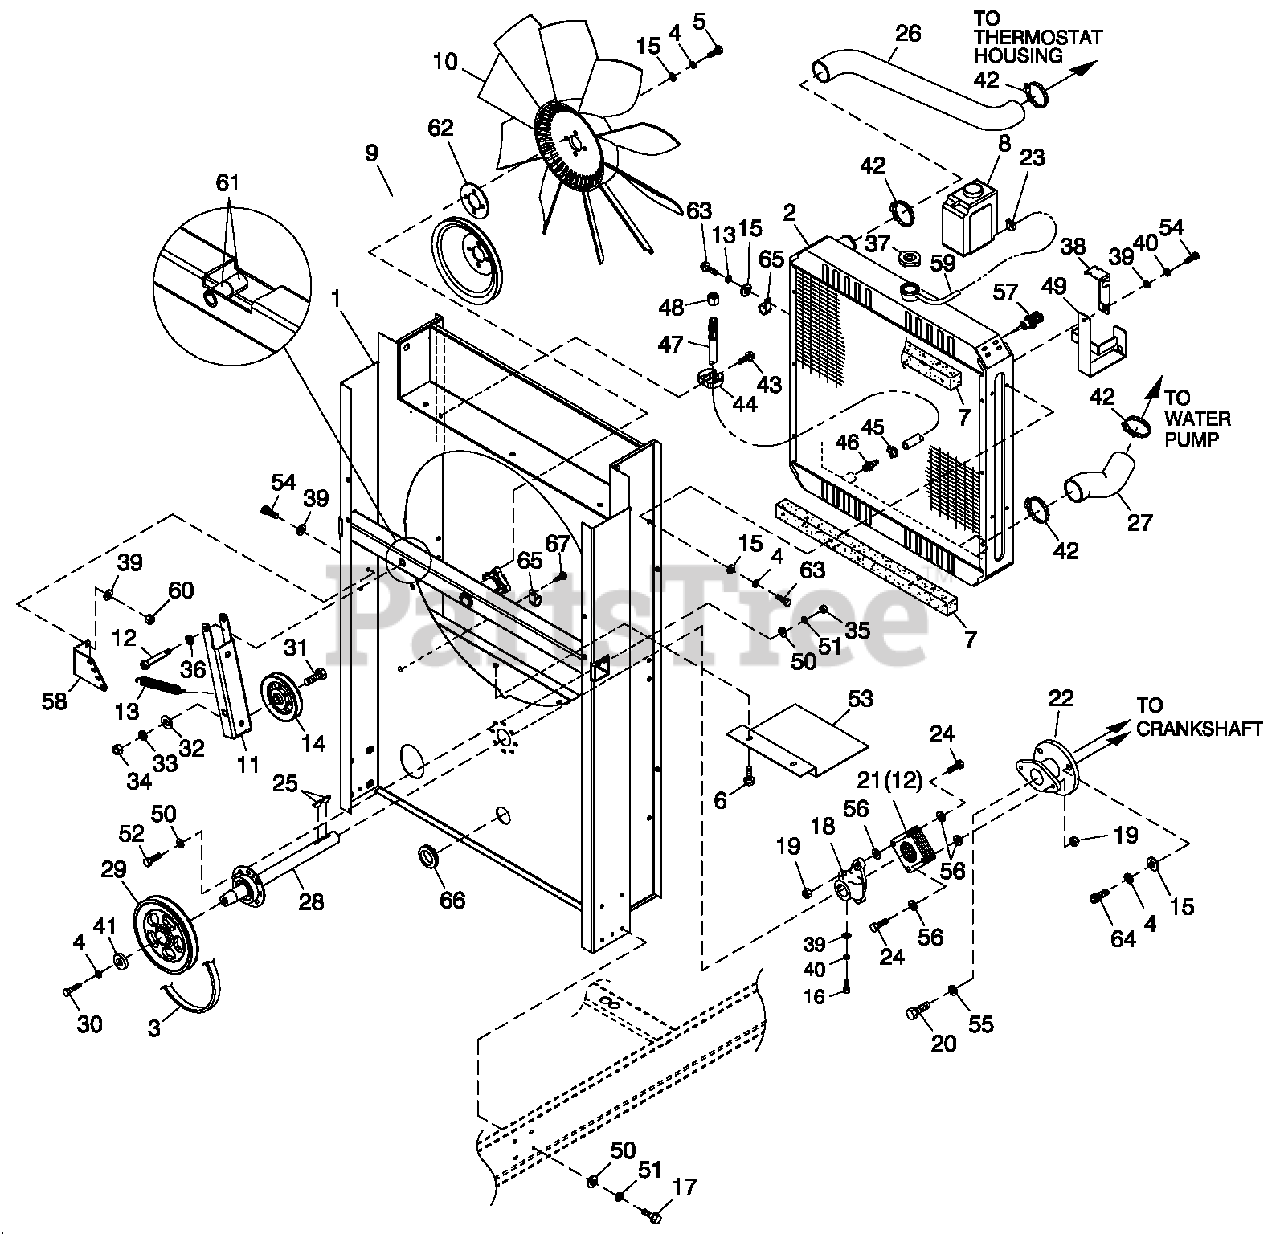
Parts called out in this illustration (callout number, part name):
1	WELDMENT RADIATOR SUPPORT C5
2	RADIATOR 680 X 680 X 70 CPL
3	V-BELT 31/64" X 62-3/8"
4	WASHER LOCK M10
5	SCREW HHC M10-1.5 X 30 C10.9
6	SCREW THF M6-1 X 16 N WA Z/JS
7	TAPE FOAM 1 X 1 (26.75" LG)
8	TANK COOLANT RECOVERY
9	PULLEY FAN V-GROOVE 9"
10	FAN 26" LH ROTATION
11	ARM BELT TENSIONER
12	SHOULDER BOLT 1/2 X 2-1/4"
13	SPRING TENSION CPL
14	PULLEY V-BELT 4" FLANGED
15	WASHER FLAT 3/8-M10 ZINC
16	SCREW HHC M8-1.25 X 45 C8.8
17	SCREW HHFC M6-1.0 X 20 G8.8
18	HUB FLEX PLATE
19	NUT HEX LOCK 5/16-24 NY INS
20	SCREW HHC M12-1.5 X 60 G8.8
21	DISK FLEX
22	COUPLING HUB FLEX (MACH)
23	CLAMP HOSE BAND 1/4
24	SCREW HHC 5/16-24 X 1.124
25	KEY WOODRUFF 4 X 19D
26	HOSE RADIATOR UPPER CPL
27	HOSE LOWER RAD CPL C5 6.8L
28	ASSY BRG/SHAFT CPL FANDRIVE
29	PULLEY 6.5" DIA MACHINED (6.8L 100KW)
30	SCREW HHC M10-1.5 X 30 G8.8
31	SCREW HHC 1/2-13 X 2" G8
32	WASHER FLAT 1/2 ZINC
33	WASHER LOCK 1/2
34	NUT HEX 1/2-13 STEEL
35	NUT HEX M6 X 1.0 G8 YEL CHR
36	WASHER NYLON .50 X .87 X .06
37	CAP RADIATOR 13 PSI
38	BRACKET, SIGNAL CONDITIONER
39	WASHER FLAT 5/16-M8 ZINC
40	WASHER LOCK M8-5/16
41	SPACER .5 X 1.5 X .25 STL/ZINC
42	CLAMP HOSE #28 1.32-2.25
43	SCREW HHTT M4-0.7 X 8 BP
44	SPRING CLIP HOLDER .37-.62
45	CLAMP HOSE .38-.87
46	BARBED STR 3/8 NPT X 3/8
47	HOSE DRAIN ASSY 28"
48	CAP HEX 1/4 NPT BRASS
49	BRACKET COOLANT TANK
50	WASHER FLAT 1/4-M6 ZINC
51	WASHER LOCK M6-1/4
52	SCREW HHC M6-1.0 X 20 G8.8
53	SHIELD RADIATOR
54	SCREW HHC M8-1.25 X 20 G8.8
55	WASHER LOCK M12
56	WASHER FLEX (THIN)
57	PROBE COOLANT LEVEL 3/8-18NPTF
58	BRACKET TENSIONER SPRING
59	HOSE 9/32 ID (43"LG)
60	NUT HEX LOCK M8-1.25 NY INS
61	BEARING SLEEVE 1/2/ X 3/4 X 1
62	SPACER CPL COOLING FAN 1/8"
63	SCREW HHC M10-1.5 X 20 C8.8
64	SCREW SHC M10-1.5 X 35 G12.9
65	CLAMP STL/VNL .62 X .406 Z
66	GROMMET 1.37 X .06 X 1.00
67	SCREW HHTT M6-1.0 X 16 ZYC
